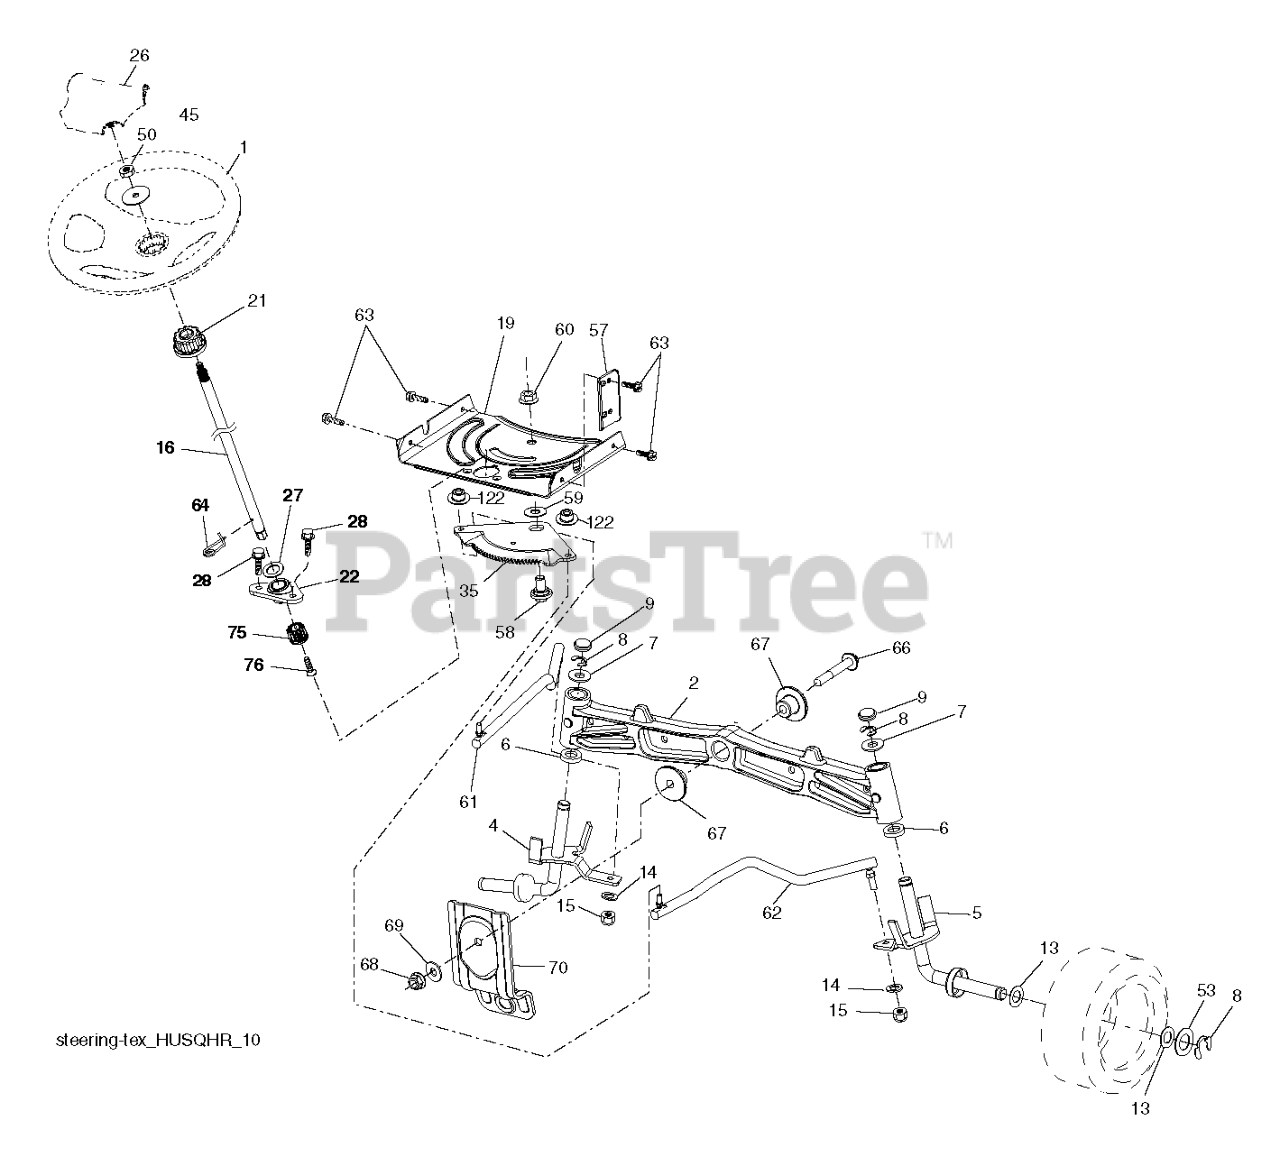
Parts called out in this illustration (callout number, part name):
1	WHEEL.STEER.HUSQ.SR.498.OVMLD
2	AXLE.CAST.IRON
4	SPINDLE.WELDED.LH.15"TEX
5	SPINDLE.WELDED.RH.15"T
6	THRUST WASHER
9	CAP.SPINDLE.BLACK
14	SLW 3/8 STD
15	NUT CROWNLOCK 3/8-24
16	SHAFT.STEER.2HIGH.SPLND.PLATED
19	PLATE.STEER.DDL.NLT/NG
21	ADAPTER.WHEEL.STEER.SPLND.ALUM
22	BEARING.SHAFT.STEER.LOWER.625
26	INSERT.CAP.WHL.STRG.HUSQ.PREM
28	SCREW, 3/8-16X3/4
35	GEAR.SECTOR.PLATE.DDL.
45	WASHER.3/8ID.2-3/8OD.12GA.PLTD
50	NUT LOCK FLG 3/8-16 UNC
53	WASHER.HARDENED
57	BRKT.UPSTOP.GT/LT.TEX
58	BOLT.SHOULDER.SECTOR.P
59	WASHER.THURST.SECTOR.S
60	NUT FLANGE LOCK 5/8-11
61	LINK.ASM.DRAG.ADJUST.LH.PLATED
62	LINK.ASM.DRAG.ADJUST.RH.PLATED
63	SCREW
64	RETAINER.CLIP.SPRING.S
66	BOLT HEX FGHD 7/16-14 X 3 SERR
67	BUSHING.PM.FRONT AXLE
68	NUT.LOCK.FLANGE.7/16
69	WASHER.1.5X.505X.118
70	BRACKET.FRT.DECK.SUSP.RR.MT431
75	PINION.ZINC PLATED
76	SCREW HEAD SOCKET LRVB
122	CAP.GEAR.SECTOR.TEX
